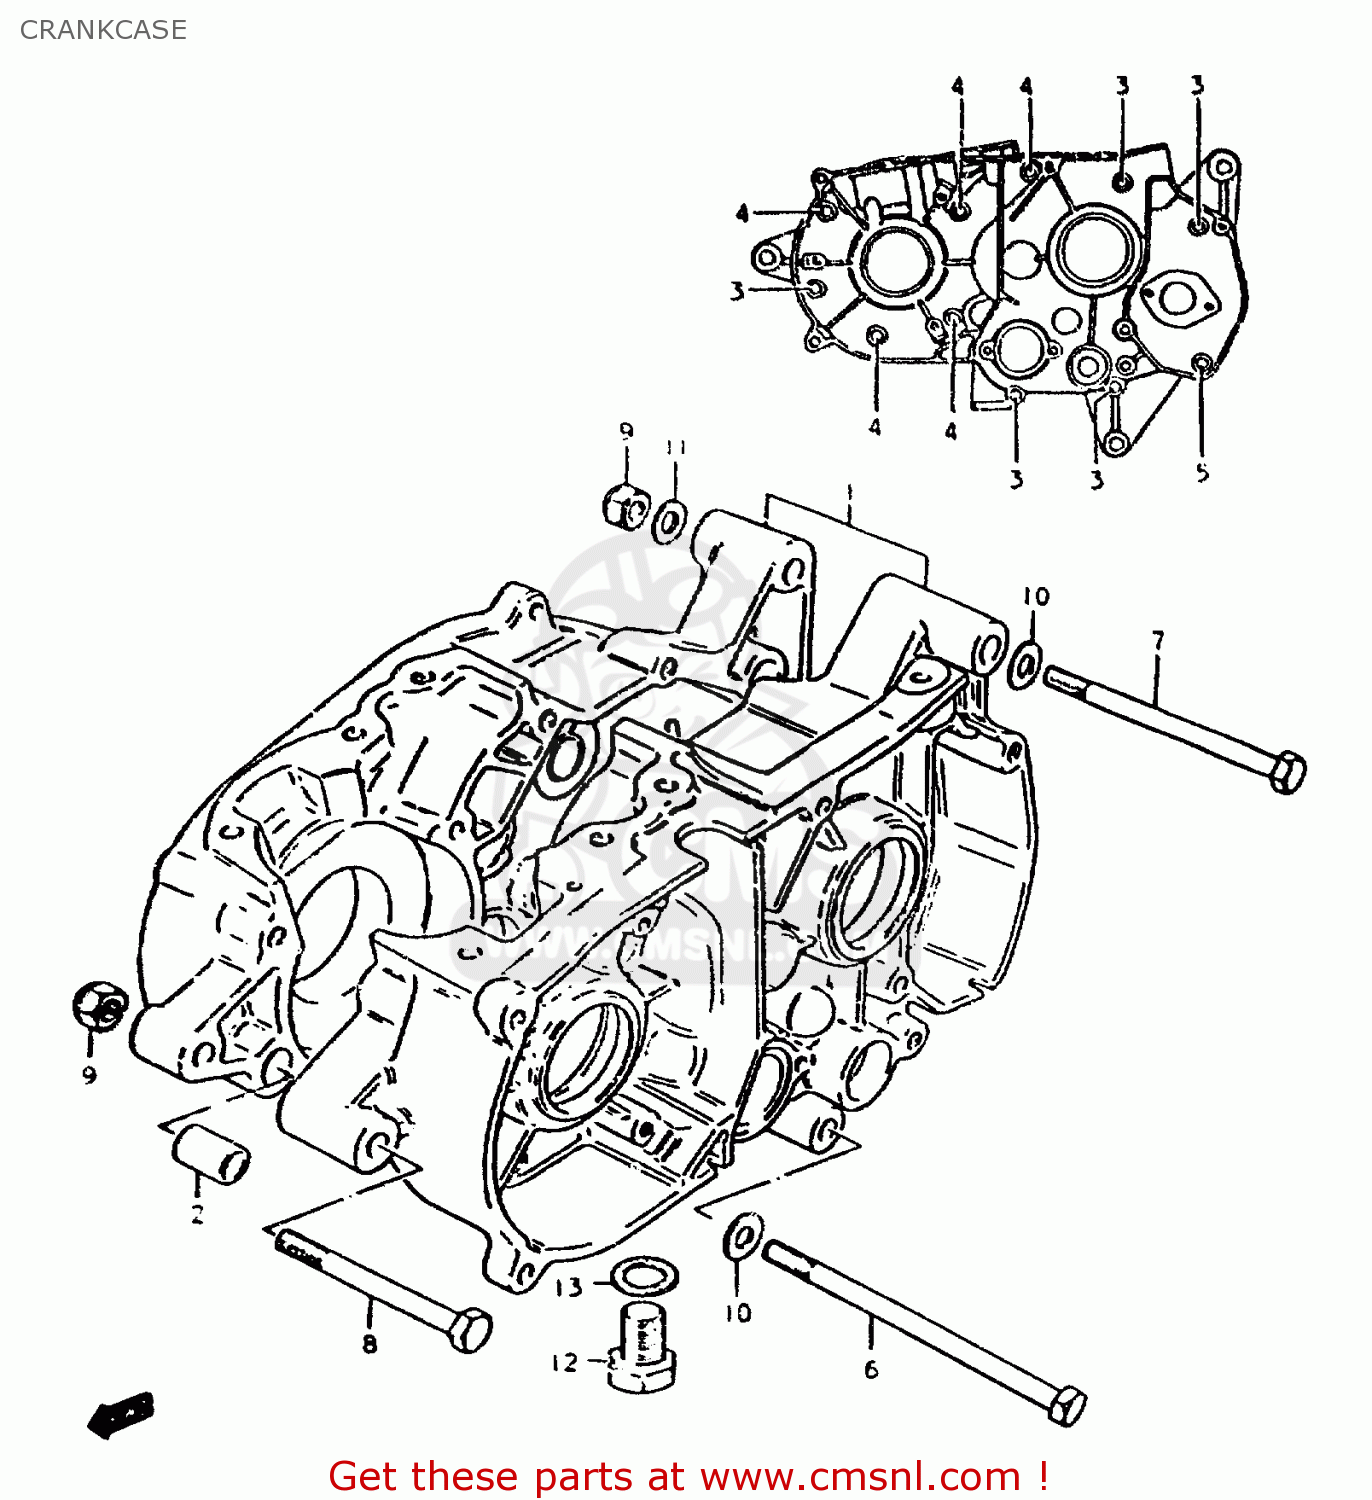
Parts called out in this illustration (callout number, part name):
1	CRANKCASE SET
2	PIN
3	SCREW (6X45)
4	SCREW (6X35)
5	SCREW
6	BOLT
7	BOLT
8	BOLT 8X75
9	NUT
10	WASHER
11	WASHER
12	BOLT 10X20
13	GASKET(10X14X3.6) (NAS)
